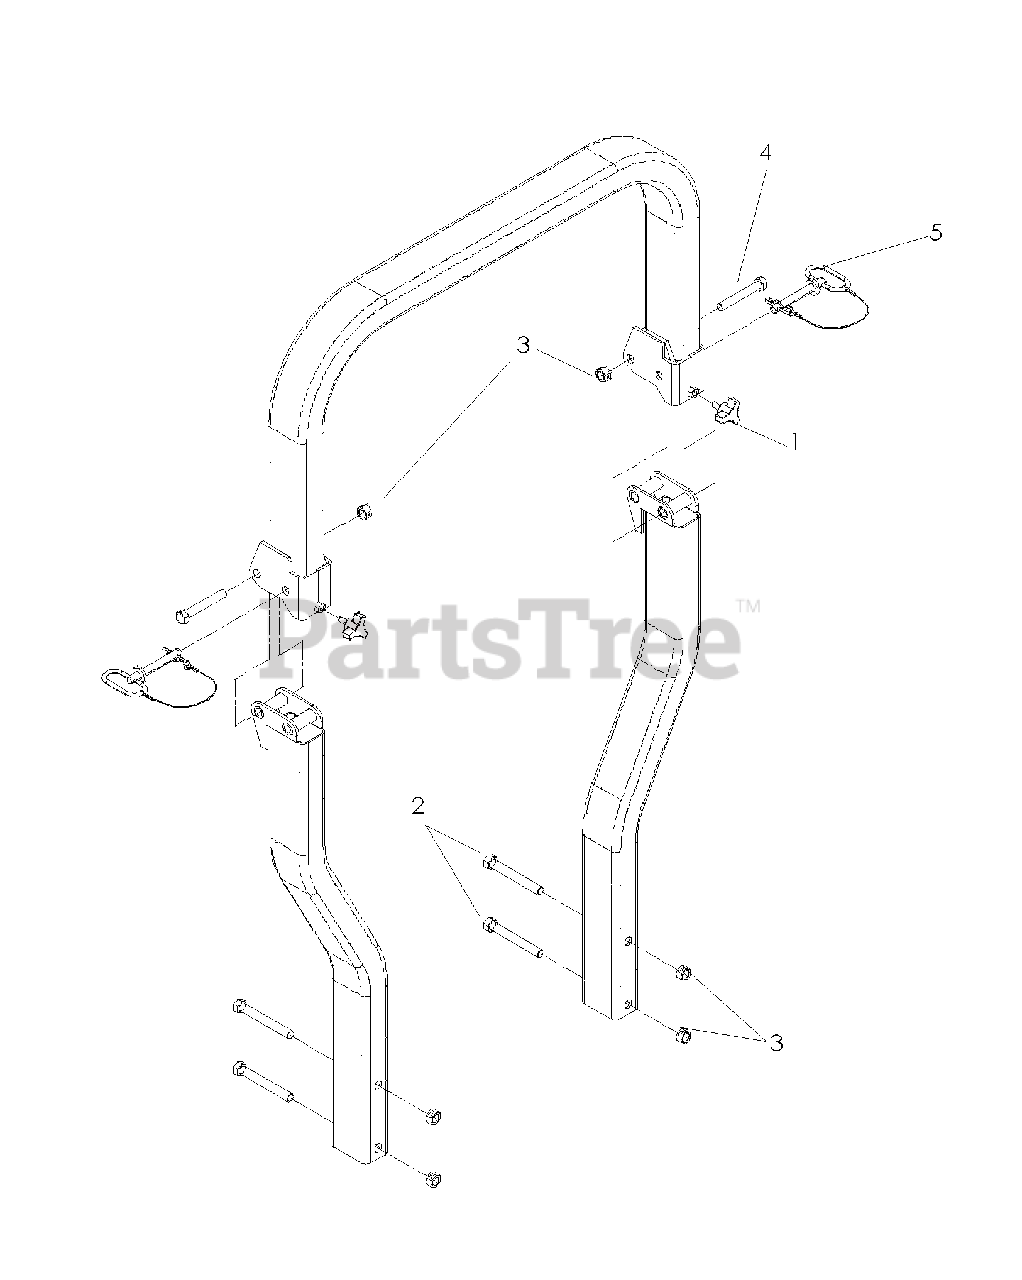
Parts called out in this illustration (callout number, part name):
1	KNOB W/STUD 3/8-16 X 1.5
2	HCS 1/2-13 X 4 GR 5 ZD
3	NUT 1/2-13 HEX CNTRLK GR 5 ZD
4	HCS 1/2C X 3 1/4
5	PIN, 1/2" W/LANYARD
